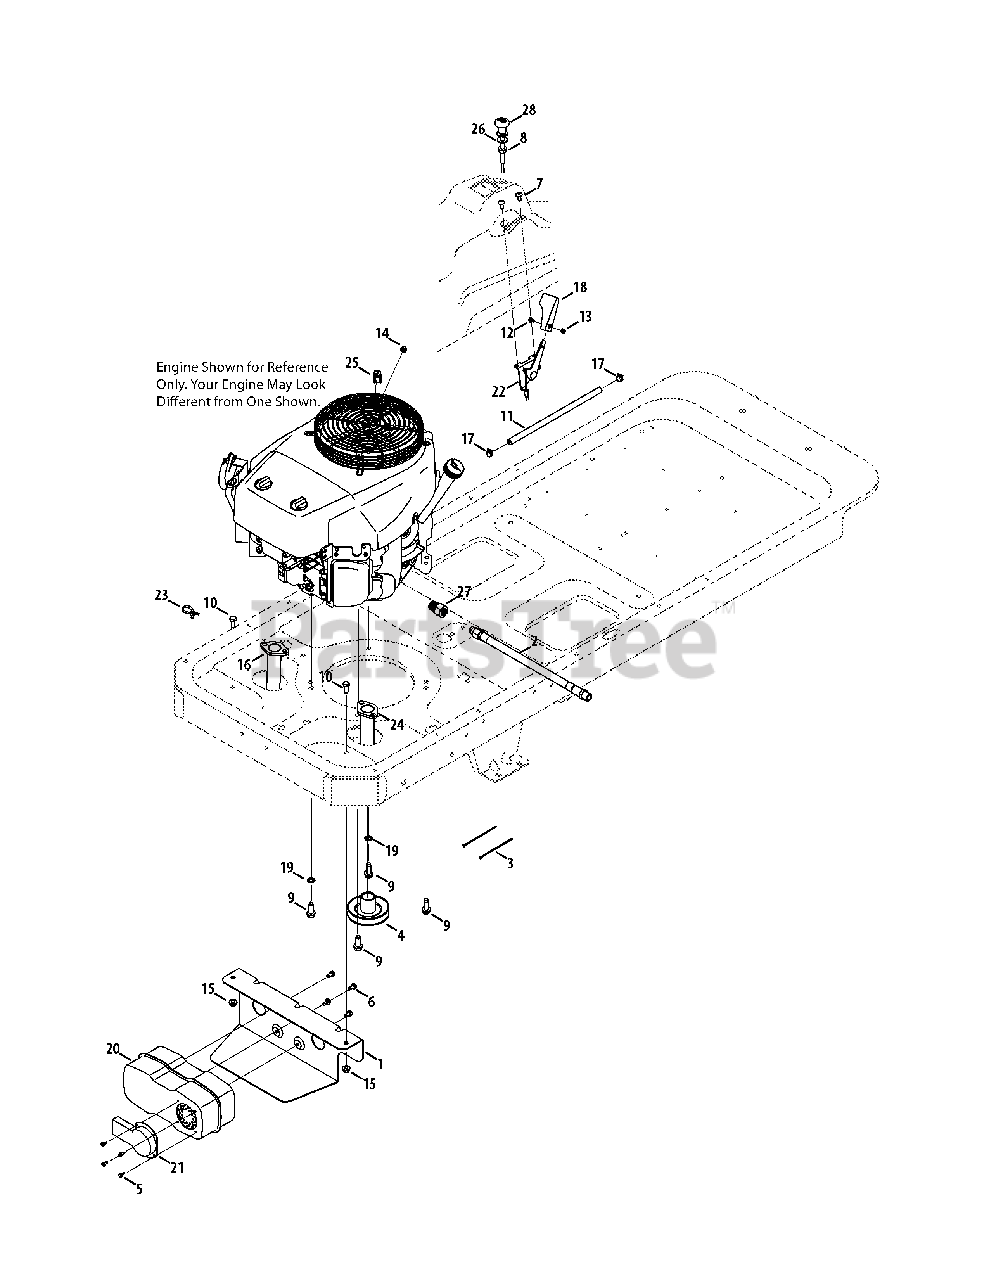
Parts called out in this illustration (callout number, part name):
1	Muffler Mount Bracket
2	Oil Drain Hose
3	Cable Tie
4	PTO Pulley
5	Hex Washer Screw, #8-18 x 0.500
6	Hex Washer Screw, 1/4-20 x 0.500
7	Screw, 1/4-14 x 0.625
8	Flange Lock Nut, 3/8-16
9	TT Screw, 3/8-16 x 1.25
10	Hex Screw, 5/16-18 x .75
11	Low Permeation Fuel Hose
12	Machine Screw, #8-32 x 0.375
13	Hex Nut, #8-32
14	Sems Nut, 1/4-20
15	Flange Lock Nut, 5/16-18
16	Exhaust Pipe - LH
17	Hose Clamp, .490
18	Throttle Control Knob
19	External Tooth Lock Washer, 3/8
20	Dual Inlet Muffler
21	Muffler Deflector
22	Throttle Cable
23	Push Mount Cable Tie
24	Exhaust Pipe - RH
26	Flat Washer, .406 x .875 x .059
28	Choke Cable
